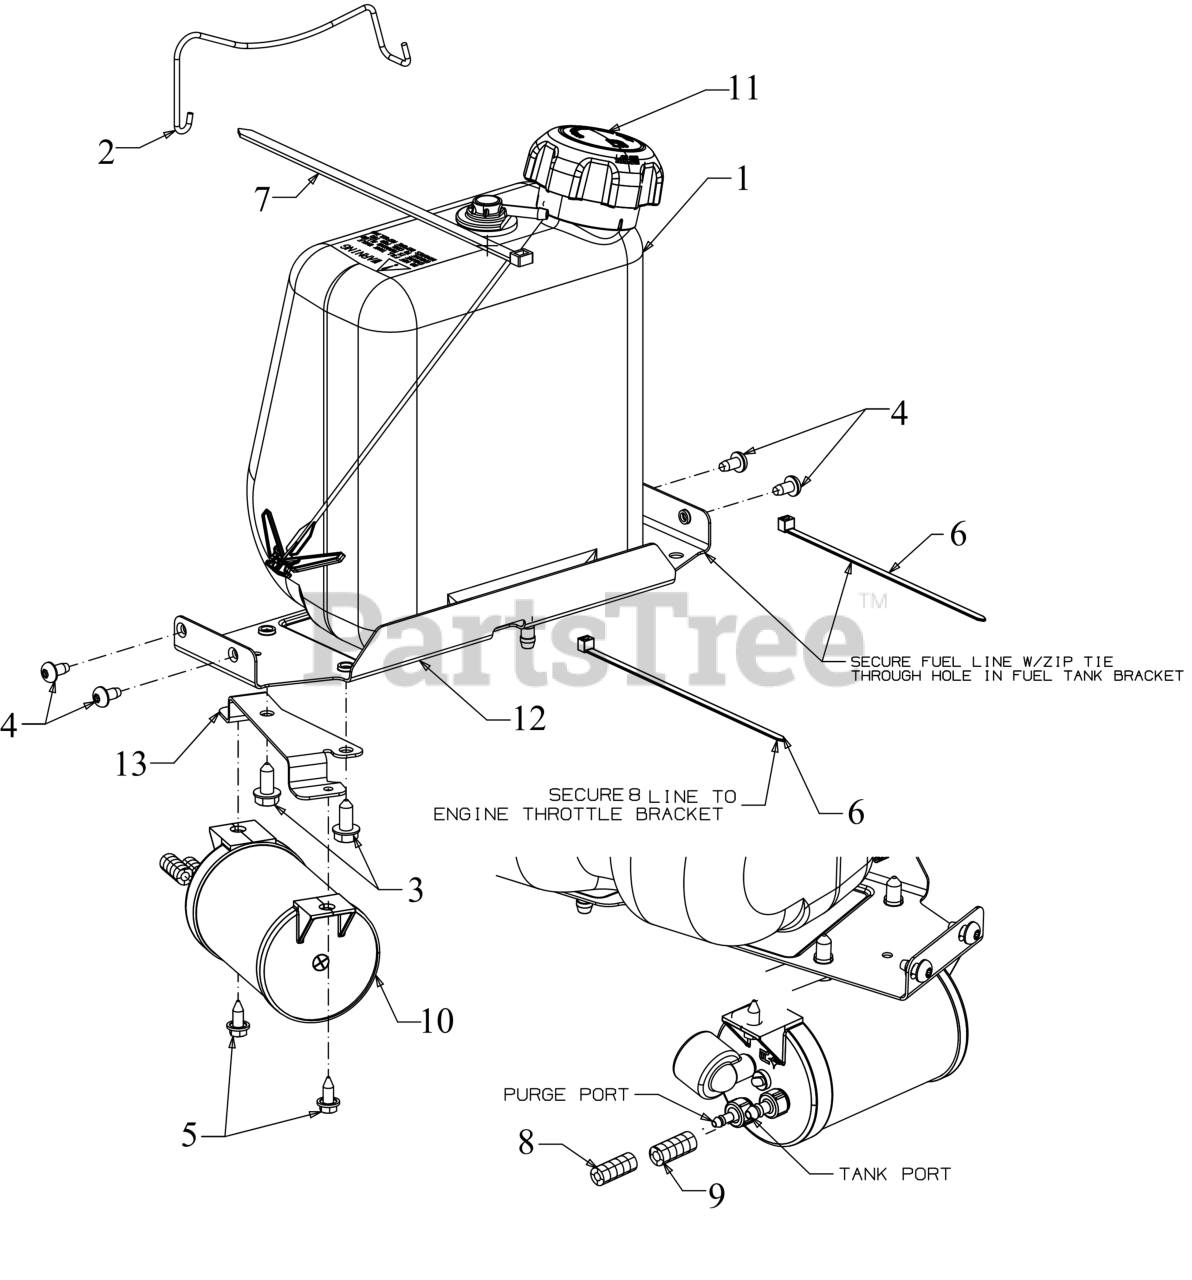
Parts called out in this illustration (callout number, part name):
1	FUEL TANK ASSEMBLY
2	BATTERY ROD ASSEMBLY (POWDER BLACK)
3	SCREW 5/16-18 x .750
4	SCREW 1/4-20 x .5
5	SCREW 1/4-20X.625
6	7" CABLE TIE
7	CABLE TIE 36"
8	FUEL HOSE LO PERMEATION 40"
9	FUEL HOSE LO PERMEATION 28"
10	CARBON CANISTER
11	FUEL CAP (W/TETHER)
12	FUEL TANK BRACKET POWDER BLACK()
